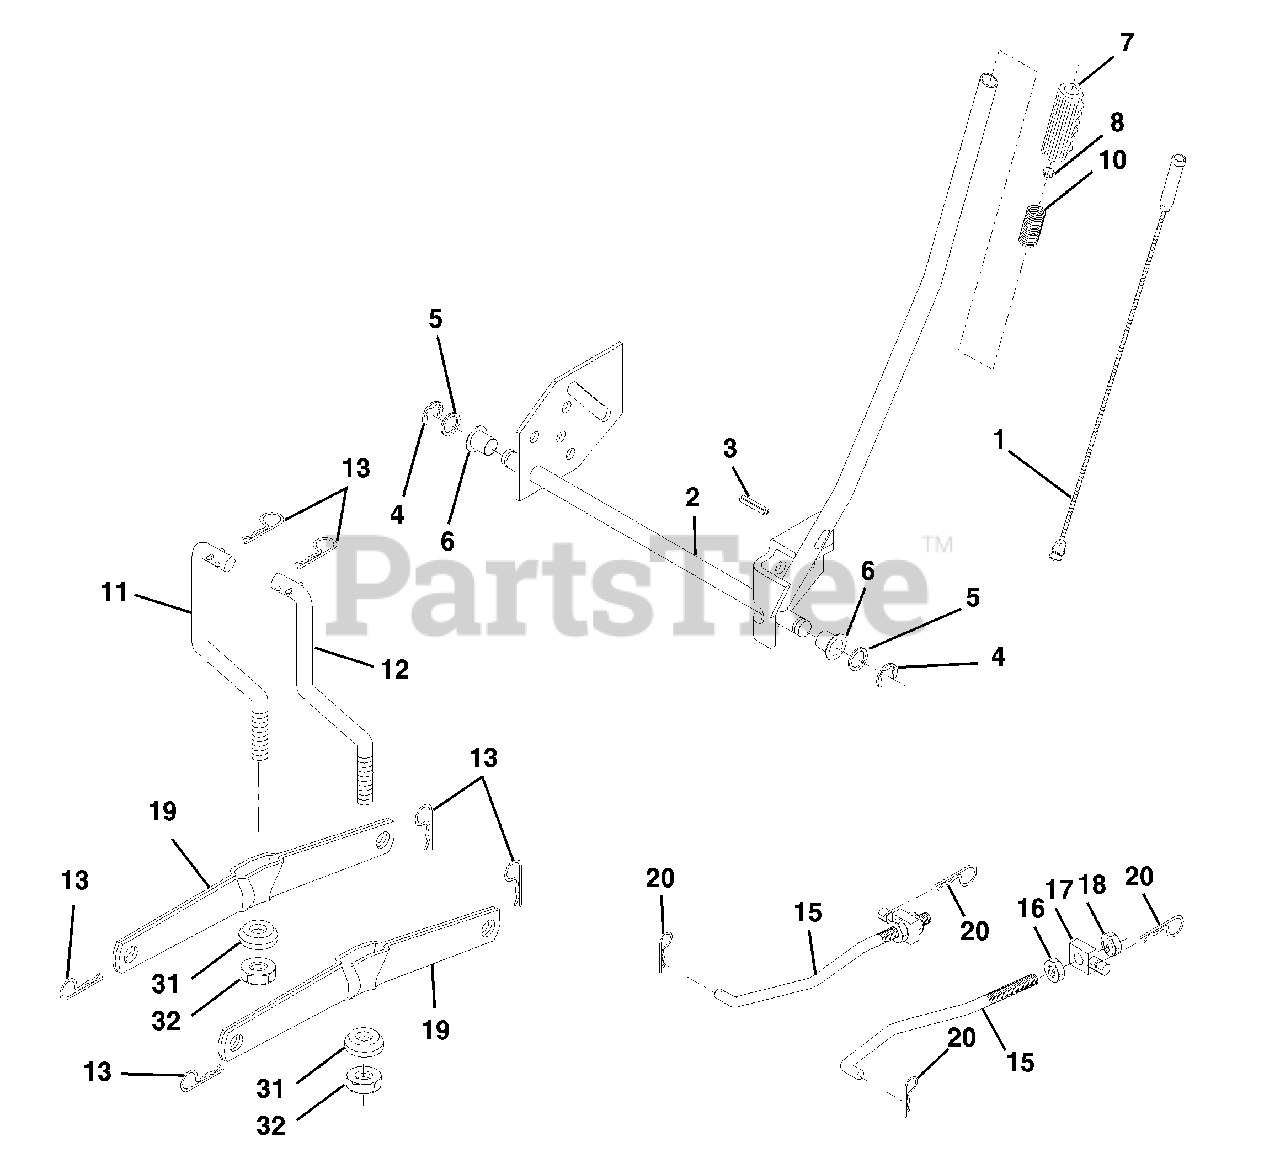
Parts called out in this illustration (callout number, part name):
1	Wire Asm Inner W/plunger 17 32
2	Shaft Asm Lift
3	Pin Groove
4	E-Ring #5133-62
5	Washer PLTD 21/32 X 1 X 21ga
6	Bearing Nylon Blk 629 Id
7	Grip Handle Bicycle
8	Button Plunger Black
10	Spring Cprsn 3 750 Oiled
11	Link Lift LH
12	Link Lift RH
13	Retainer Spring
15	Link Front
16	Nut Jam Hex 1/2-13 Unc
17	Trunnion Blk Zinc
18	Nut Lock W/wsh 1/2-13unc
19	Arm Suspension Rear
20	Spring, Retainer
31	Bearing Pvt. Lift Spherical
32	Nut Crownlock 3/8-24
